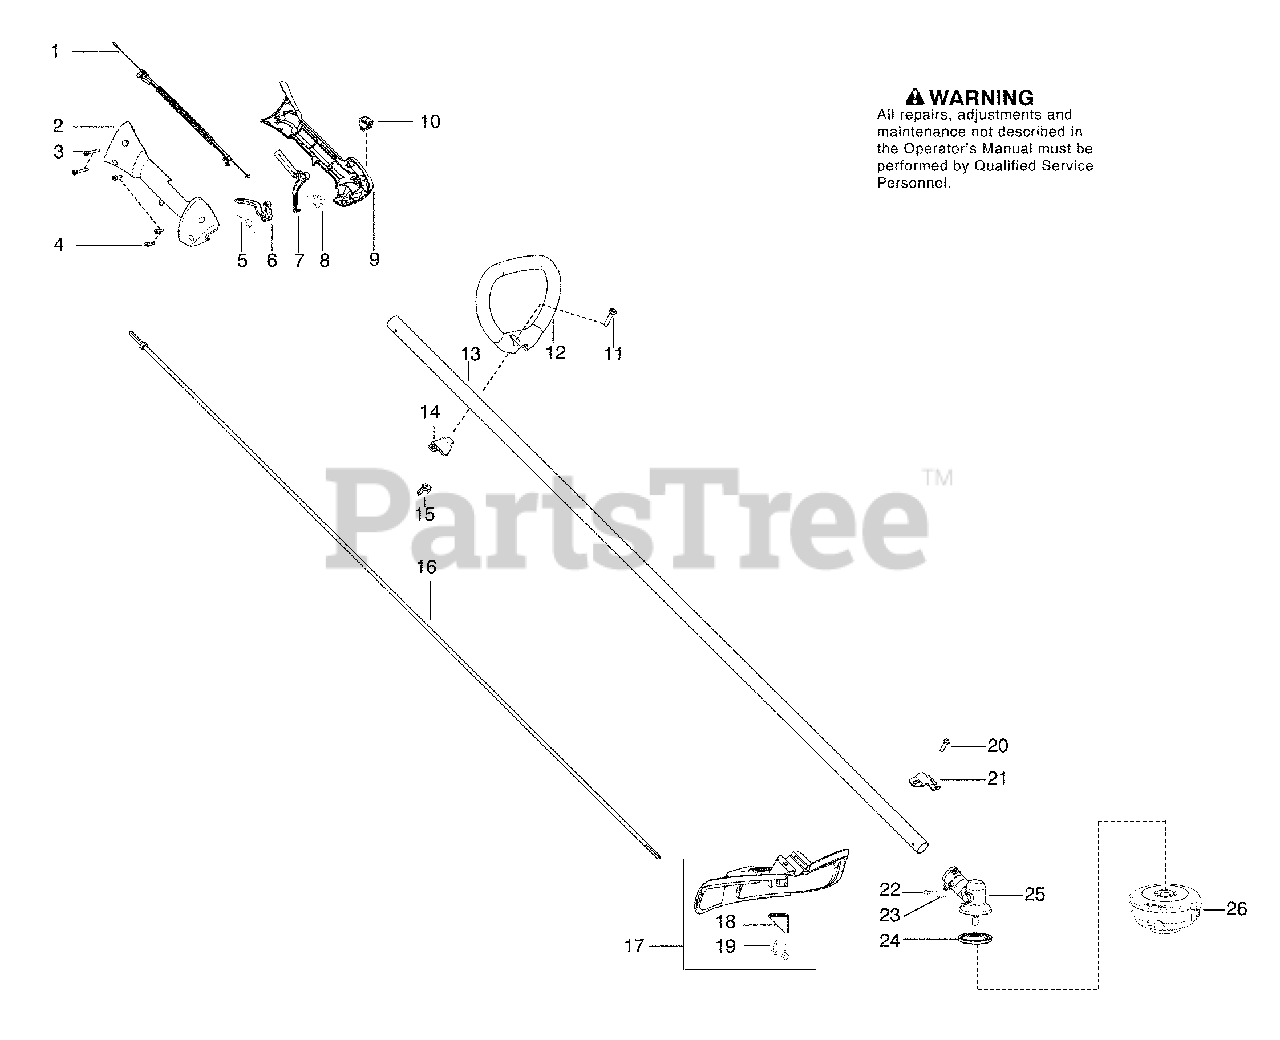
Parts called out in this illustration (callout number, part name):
1	Assy-Cable/Wire Harness
2	Housing-Throttle (RH)
5	Spring-Trigger
7	Lockout-Throttle
8	Spring-Lockout
9	Housing-Throttle (LH)
10	Kit-Switch
12	Handle-Assist
13	Kit-Driveshaft SST
14	Clamp-Handle
15	Wingnut
16	Flex shaft
17	Kit-Shield
18	Limiter-Line
21	Bracket-Shield
24	Driver Disc
25	Assy-Gearbox
26	Assy-T25 Cutting Head
